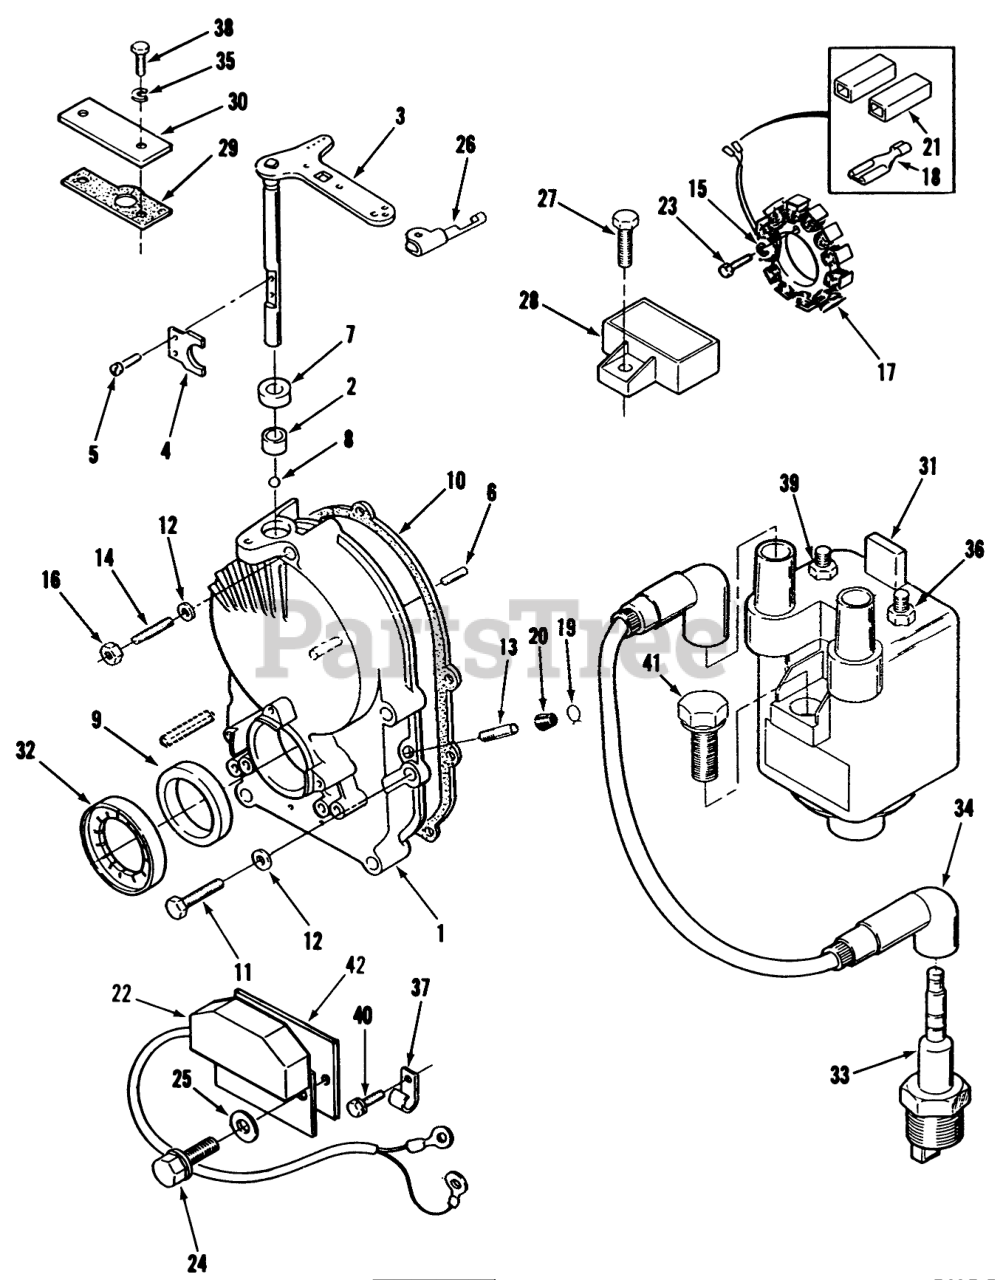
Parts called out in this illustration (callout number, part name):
1	Gearcase Kit (Includes Items 2 thru 9, 13, 19 & 20)
2	BEARING
3	SHAFT AND ARM
5	SCREW-PAN HD
6	Washer
10	Gasket
11	Screw 5/16-18 1-3/4
12	WASHER
13	TUBE-PORT, VACUUM
14	Stud
15	WASHER-LOCK
16	Nut
17	Stator
18	Stator Leads Terminal
19	CLAMP
20	CAP-FUEL OUTLET
21	Terminal Connector Body Kit (Includes Terminals)
22	Control-Ignition
23	Bolt
24	Bolt
25	Lockwasher
27	Bolt
28	Regulator
29	Gasket
30	Plate
31	Coil-Ignition
32	Rotor
33	SPARK PLUG
34	CABLE KIT
35	NUT-HEX M6
36	Nut
37	Clip
38	Bolt
39	Nut
40	Screw-Cap Hex Hd.
41	Bolt
42	Insulator
